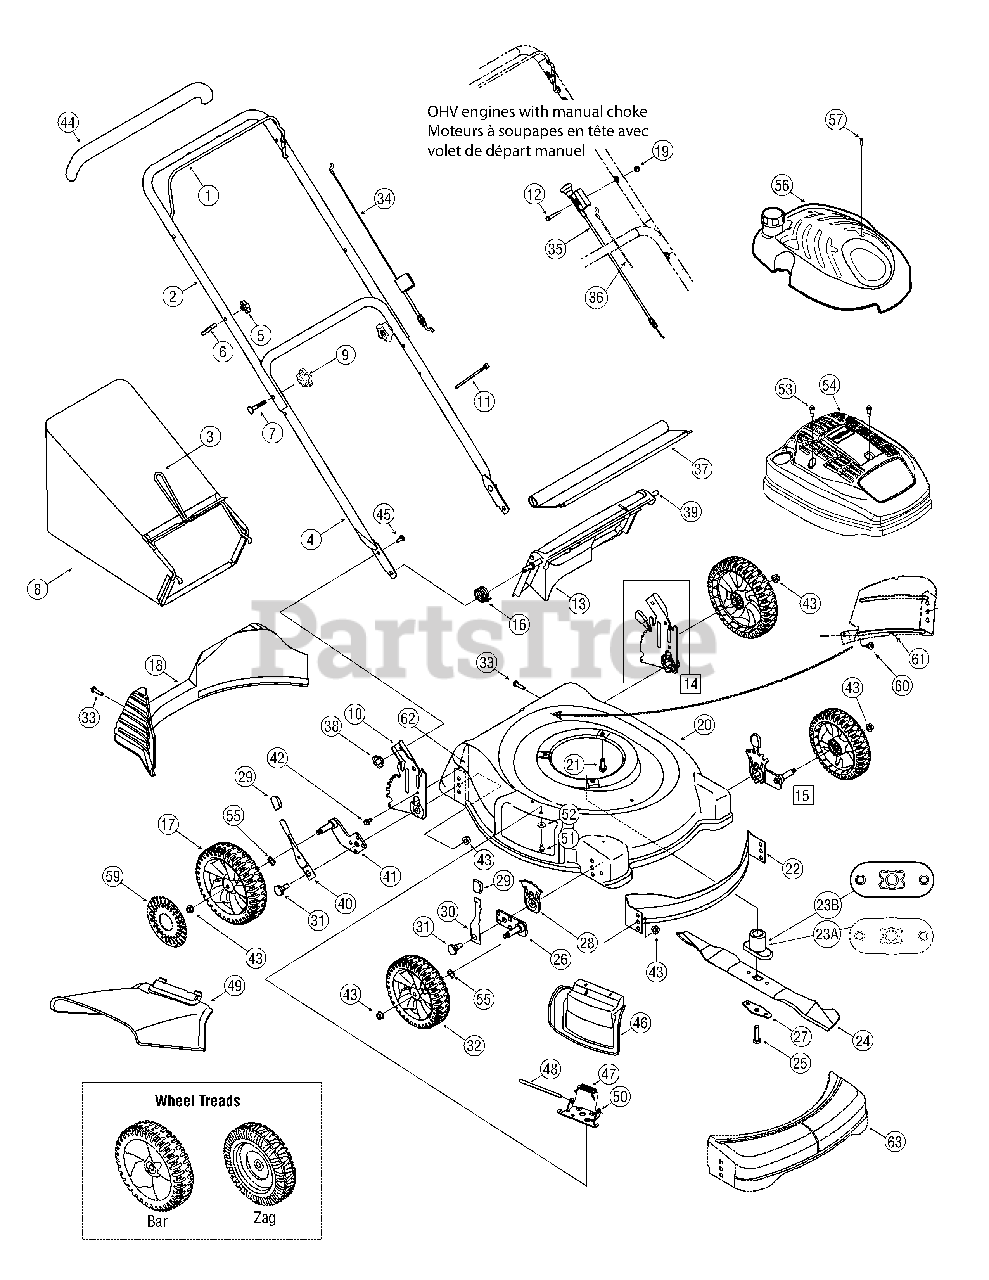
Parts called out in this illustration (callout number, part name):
1	Blade Control Handle - Black
2	Upper Handle - Black
5	Knob 1/4-20
6	Rope Guide Bolt
7	Curved Carriage Bolt 5/16-18 x 2.00
8	Generic Grasscatcher Bag
9	Knob - Star 5/16-18
10	LH Height Adj. Brkt.
10	RH Height Adj. Brkt.
11	Cable Tie
12	Hex Cap Screw1/4-20 x 1.5" Lg.
13	RB Chute Door
14	LH Rear Height Adj. Ass’y Complete
14	RH Rear Height Adj. Ass’y Complete
15	Height Adj. Ass’y LH (w/8" Frt Wheels)
15	Height Adj. Ass’y RH (w/8" Frt Wheels)
16	Torsion Spring RH
17	Wheel Ass'y 8 x 2.125 Idle BB Zag
18	RR Baf fle
19	Flange Locknut 1/4-20
20	21" Deck Ass’y (w/ side discharge)
21	Hex Wash HD Tap Scr 3/8-16 x .88
22	Front Baffle 21"
23	Blade Adapter 25 mm x 2.15 (w/star)
24	21" Blade (w/star)
24	21" Mulching Blade (w/star)
25	Hex Bolt 3/8-24 x 2.5" Lg. Gr. 8
26	Pivot Bar RH
26	Pivot Bar LH
27	Blade Bell Support
28	Height Adjuster Plate
29	Knob
30	Spring Lever Ass’y (w/o knob)
31	Shoulder Screw .50 Dia.
32	Wheel Ass'y 8 x 2.125 Idle BB Zag
33	Hex. L-Scr. 1/4-15 x 1.0
34	Control Cable 40.0" Lg. Snap-on
35	Choke Cable Ass'y 38.0" Lg.
36	ERS Cable Control 48.0 (w/manual choke)
37	Rear Flap
38	Wingnut 1/4-20
39	Pivot Rod
40	Spring Lever SP (w/knob)
41	Pivot Bar RH SP
42	Hex HD. TT Tap Scr. 1/4-20 x 5/8
43	Flange Locknut 3/8-16
44	Snap-On Bail Cover -Black
45	Carriage Bolt 1/4-20 x .75 Gr. 1
46	Complete Hinged Mulching Plug Ass'y
47	Torsion Spring
48	Hinge Pin
49	Chute Deflector
50	Chute Adapter
51	Hex Wash S-Tapp Scr 1/4-20 x .50
52	Cupped Washer .265 ID x .75 OD x .062
55	Wave Washer (w/ball brg wheels only)
57	Screw (w/inserts in engine for shroud)
57	Screw (w/o inserts in engine for shroud)
59	Hub Cap -Grey
60	Screw 1/4-14 x .625
61	LH Rear Baffle
62	RH Rear Baffle
